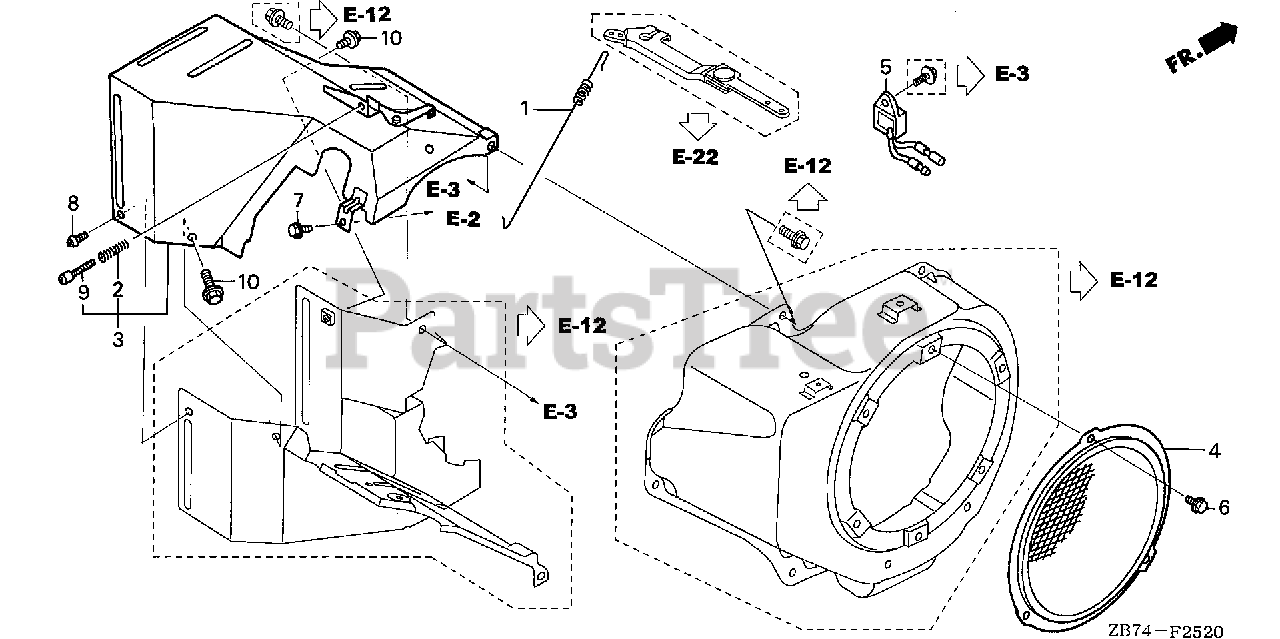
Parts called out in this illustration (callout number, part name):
1	SPRING, GOVERNOR (L=145.0MM) (WIRE DIAMETER 1.0MM)
2	SPRING, CONTROL ADJUSTING Use from Engine SN 2327377.
3	SHROUD ASSY. (UPPER)
4	PROTECTOR, FAN COVER *R280* (POWER RED)
5	ALERT UNIT, OIL
6	BOLT, FLANGE (6X10)
7	BOLT, FLANGE (6X12) (CT200)
8	SCREW, PAN (5X8)
9	SCREW, PAN (5X32)
10	BOLT, FLANGE (6X8)
